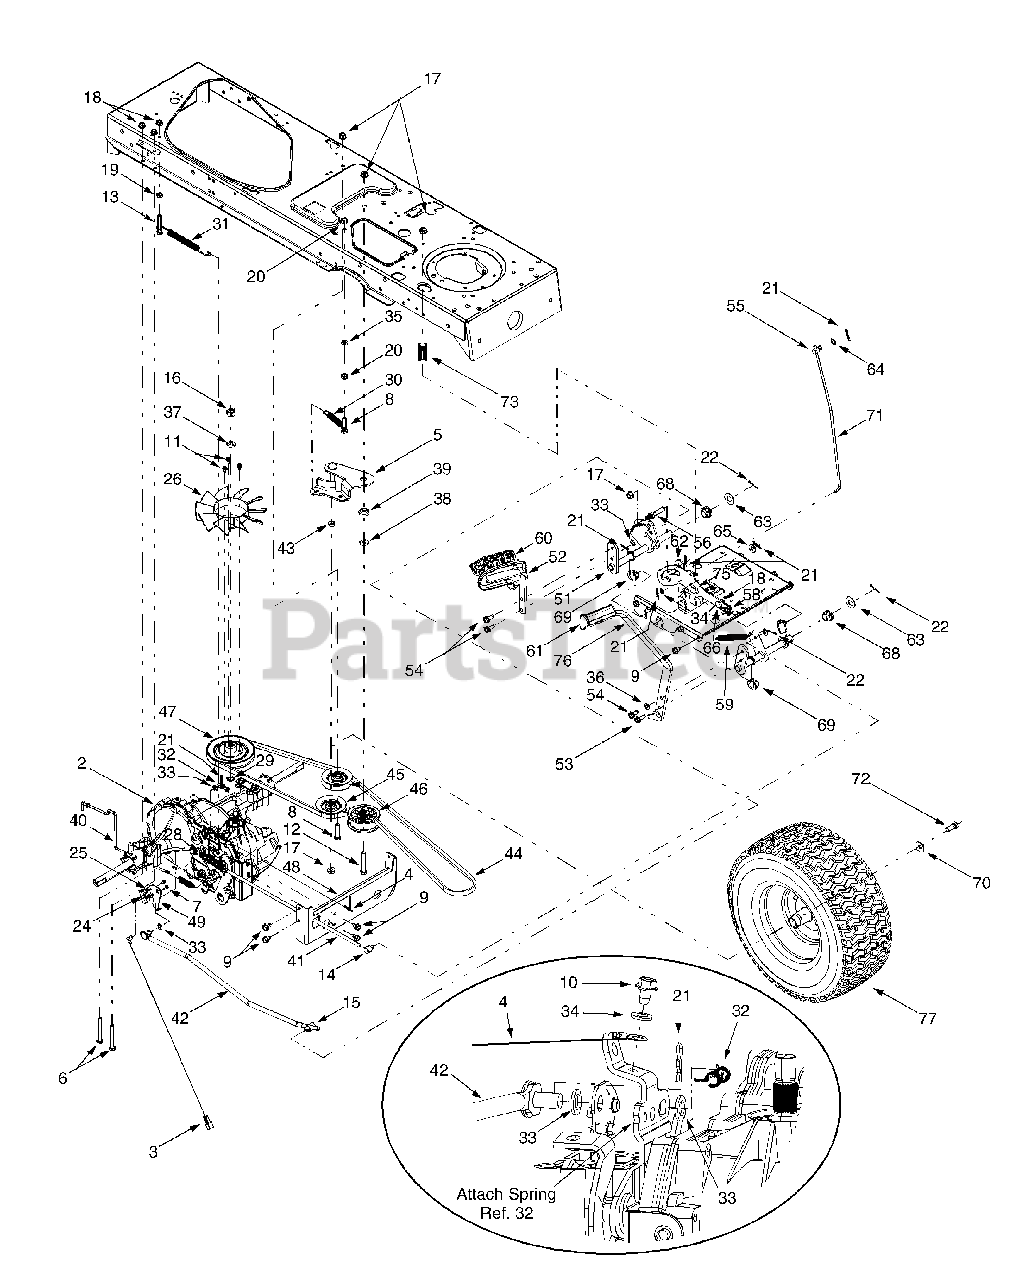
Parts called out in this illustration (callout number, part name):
2	Hydrostatic Transmission
3	Reverse Wire Harness Adapter
4	Reverse Wire Harness Ground
5	Double Idler Bracket Assembly
6	Hex Cap Screw, 5/16-18 x 2.75
7	Screw, #8-18 x .5
8	Hex Cap Screw, 3/8-16 x 1.5
9	Self-tapping Screw, 5/16-18 x .625
10	Self-tapping Screw, 1/4-20 x .375
11	Screw, #12-24 x .375
12	Hex Cap Screw, 3/8-16 x 2.25
13	Hex Cap Screw, 5/16-18 x 2.0
14	Ferrule, 5/16-18
15	Ferrule, 3/8-24
16	Hex Nut, 1/2-20
17	Flange Lock Nut, 3/8-16
18	Flange Lock Nut, 5/16-18
19	Hex Nut, 5/16-18
20	Hex Nut, 3/8-16
21	Internal Cotter Pin
22	Cotter Pin
24	Short Spring Switch
25	Insulator Nut Plate
26	10-inch Fan
28	Extension Spring, .59 x 4.0
29	Wire Ring
30	Extension Spring, .5 x 3.5
31	Extension Spring, .5 x 7.0
32	Extension Spring, 3/8 x 1.44
33	Flat Washer, .385 x .62 x .063
34	Flat Washer, .281 x .50 x .063
35	Lock Washer, 3/8
36	Flat Washer, .344 x .688 x .065
37	Lock Washer, 1/2
38	Flat Washer, .407 x .812 x .135
39	Shoulder Spacer, .38
40	Hydrostatic Bypass Rod
41	Hydrostatic Brake Rod
42	Hydrostatic Control Rod
43	Spacer, .376 x .625 x .22
44	Drive Belt
45	V-idler Pulley, 3.06
46	Flat Idler Pulley, 2.75
47	Input Pulley, 5.0
51	Drive Control Assembly
52	Hydro Pedal Assembly
53	Self-tapping Screw, 5/16-18 x .875
54	Self-tapping Screw, 5/16-18 x .75
55	Ferrule, 1/4-20
56	Pin, 3/8-16 x 2.43
58	Extension Spring, .50 OD x 1.41
59	Extension Spring, .50 OD x 6.37
60	Drive Pedal Pad
61	Brake Pedal Pad
62	Flat Washer, .411 x 1.25 x 1.0
63	Flat Washer, .64 x 1.24 x .06
64	Flat Washer, .344 x .062 x .03
65	Flat Washer, .406 x .875 x .105
66	Shoulder Screw, .437 x 1.62
68	Hex Flange Bearing
69	Split Hex Flange Bearing
70	Bell Washer, .34 x .872
71	Brake Lock Control Rod
72	Hex Cap Screw, 5/16-24 x .75
73	Spacer, 5/16 x 1.54
75	Drive Lockout Bracket
